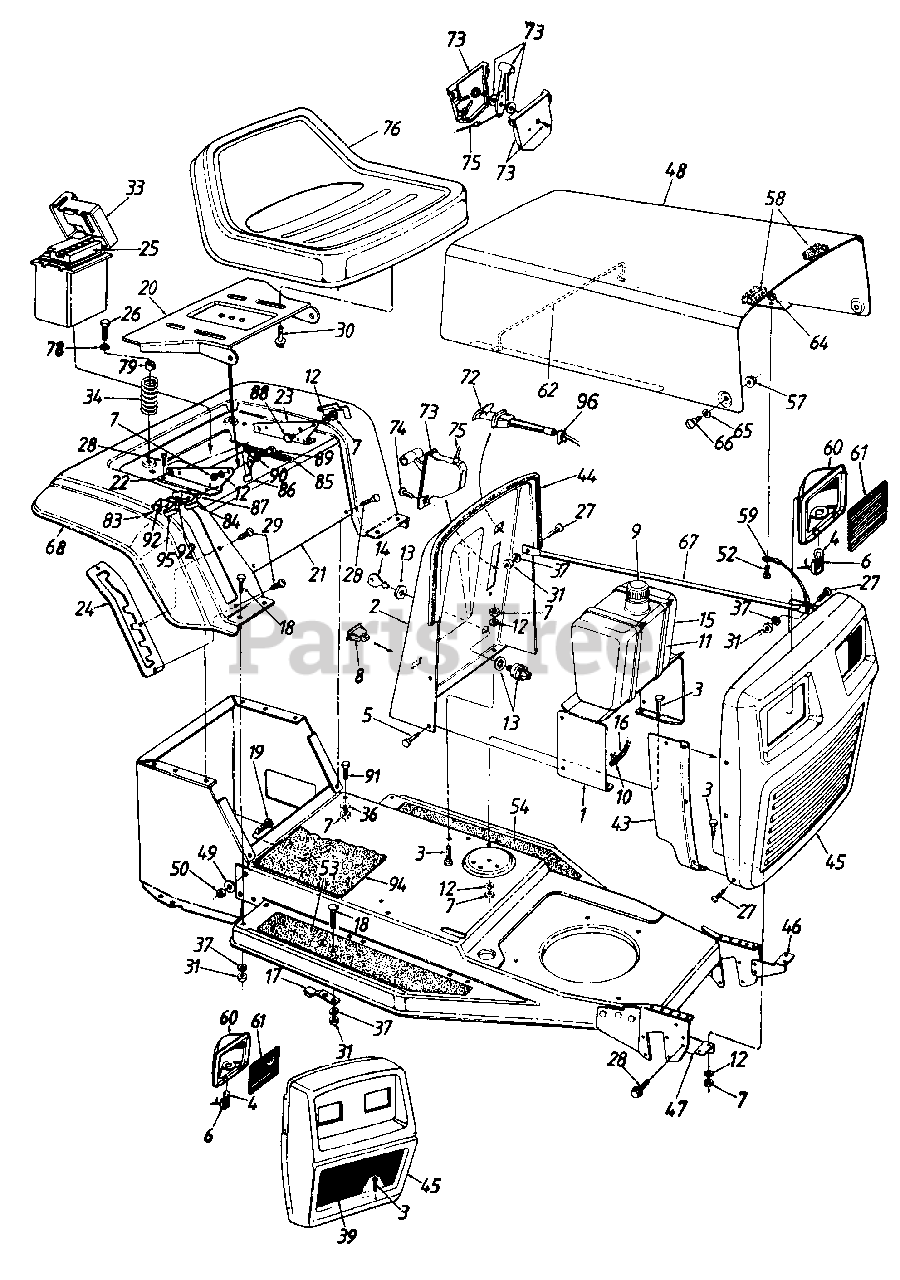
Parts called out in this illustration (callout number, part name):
1	Dash Panel Support Brkt
4	Bulb
5	Hex AB-Tap Scr. 1/4 x .62"
6	Socket
7	Hex Nut 5/16-18 Thd.
8	Light Switch
9	Gas Cap
10	Hose Clamp
11	Cable Tie
12	L-Wash. 5/16" I.D.
13	Ignition Switch
14	Ignition Key
15	Fuel Tank
16	Gas Line 15" Long
17	Blade Brake Ass'y.
18	Carriage Bolt 1/4-20 x .62"
19	Ribbed Neck Bolt 3/8-24 x .8"
20	Seat Pivot Brkt.
25	Battery
26	Hex Self-Tap Screw 5/6-18 x 1.25" Lg.
27	Truss Mach. Scr. 1/4-20 x .75" Lg.
28	Hex AB-Tap Scr. 5/16 x .75" Lg.
29	Torx Mach. AB-Tap Scr. 1/4 x .62" Lg.
30	Hex Self-Tap Scr. 3/8-16 x .75" Lg.
31	Hex Nut 1/4-20 Thd.*
33	Battery Box w/Cover
34	Compression Spring
36	Bell-Wash. 5/16" I.D.
37	L-Wash. 1/4" I.D.
39	Grille Insert
44	Trim Strip 31" Lg.
47	Grille Mtg. Brkt.-R.H.
50	Hex L-Nut 3/8-24 Thd.
52	Truss Mach. Scr. #10-24 x .5" Lg.
53	Foot Pad-R.H.
54	Foot Pad-L.H.
57	Lock Nut 1/4-28 Thd.
58	Foam Strip
59	Hood Stop
60	Headlight Housing
61	Lens
62	Hood Spring
64	Hex Sems Nut #10-24 Thd.
65	Spr. Wash. .39" I.D. x .62" O.D.
66	Shld. Bolt
67	Grille Support
68	Trim Strip 81" Lg.
72	Choke Control
73	Throttle Control Box
74	Truss AB-Tap Scr. #10 x .5"
75	Throttle Wire
76	Seat Assembly
78	Fl-Wash. .344" I.D. x .88" O.D.
79	Bushing
83	Hex Tap Scr. #8 x .5" Lg.
84	Safety Switch
85	Ext. Spring 5.31" Lg.
86	Seat Lift Brkt.
87	Insulator Boss Plate
88	Shld. Bolt .437" Dia. x .162" Lg.
89	Shld. Bolt .437" Dia. x .268" Lg.
90	Spr. Wash. .445" I.D. x .75"
91	Hex Wash. Hd. Scr. 5/16-18 x .62" Lg.
92	Insulator Plate
94	Center Foot Pad
95	Safety Switch
96	Retainer Clip
